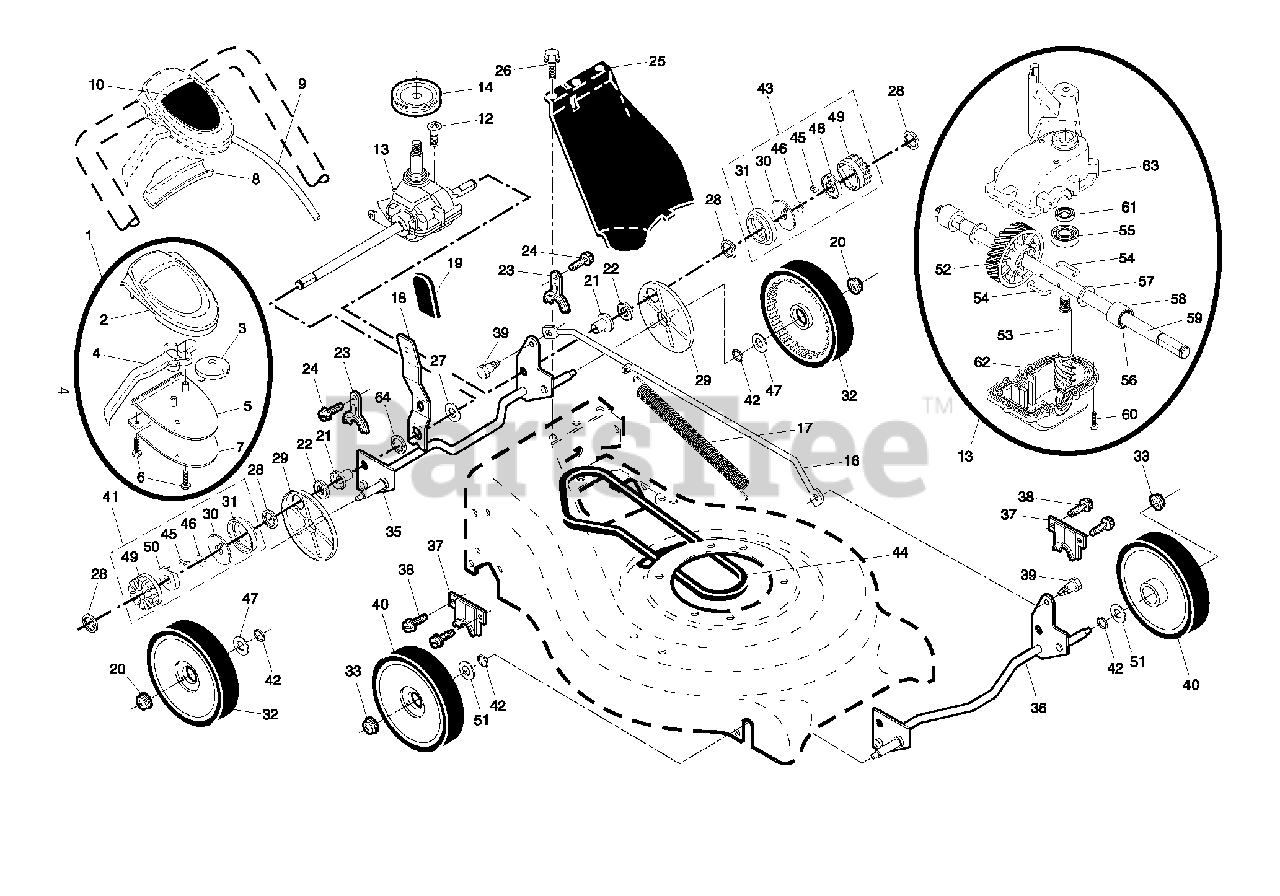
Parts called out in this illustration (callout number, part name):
3	PULLEY, DRIVE CONTROL
6	SCREW, PHILLIPS HEAD 10 X 5/8
7	BRACKET.DRIVE.CONTROL.MOUNT
8	EA WLK COVER PLATE.BLK
9	CABLE.ASM.
13	TRANSMISSION.21.RWGD
14	PULLEY.1.PIECE
16	ROD.CONNECTING.SPT.BLACK
17	SPRING
18	SPRING.SELECTOR.SPT.21
19	KNOB, SELECTOR SPRING
20	HEX FLANGE LOCKNT
21	RP BEARING SUPPORT
22	BEARING, BALL
23	BRACKET
28	E-RING 7/16 RE
29	COVER.DUST.WHEEL
30	DISC.DRIVE.21.EZ-WALK
31	SEAL.PINION
33	HEX FLANGE LOCKNT
35	SHAFT ASSY REAR
37	RETAINER.FRONT.SHAFT
39	SHOULDER BOLT SEMI GIMLET PT.
41	PINION ASSY, RH
42	O-RING..070X.487.NEOPRENE
43	PINION ASSY, LH
44	BELT.DRIVE.EZ.WALK.HI-VAC
45	PAWL.DRIVE.21.EZ-WALK
46	SPRING, TORSION
47	WASHER FLUT
48	RETAINER.DRIVE.21.EZ-WALK.LT
49	GEAR, PINION
50	RETAINER, DRIVE, RH
51	WASHER PM
52	GEAR.24.TOOTH.WALK.MOWER
53	SHAFT INPUT
54	WIRE, FORMED
56	SEAL.OUTPUT.SHAFT
59	SHAFT.OUTPUT.RGD.VS/EZ
61	SEAL INPUT SHAFT
62	CASE, LOWER
63	CASE, UPPER
